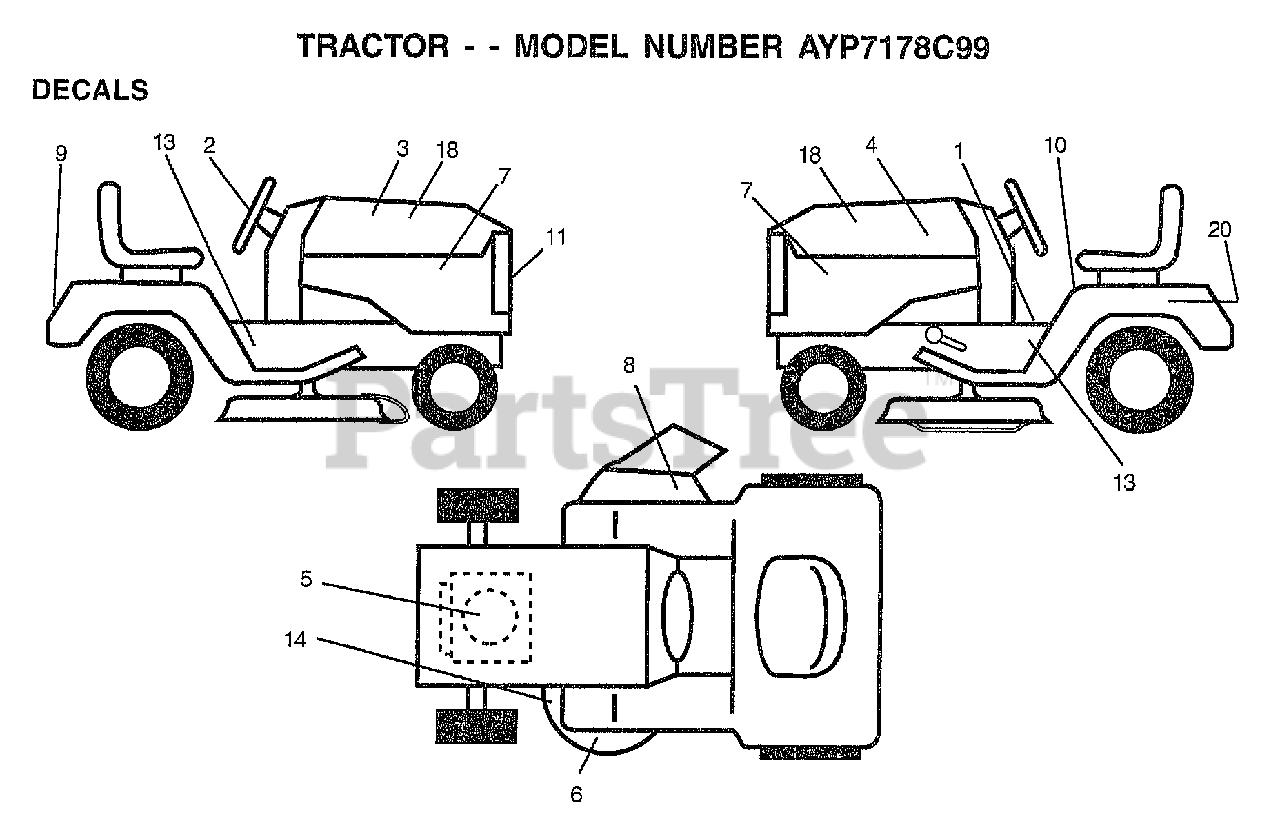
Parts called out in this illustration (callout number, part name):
1	"DECAL-DASH,OPER"
2	DECAL STEER WHL
3	DECAL HOOD RH
4	DECAL HOOD LH
5	DECAL, HP ENGINE
6	DECAL DECK MULCH
7	DECAL.SIDE PANEL
8	DECAL DECK WIZ +
10	"DECAL DANGER,FEND"
11	DECAL.LENS.WIZARD
13	DECAL CHASSIS WIZ
14	"DECAL-SCHEM,BELT"
18	NAMEPLATE.HD.WIZA
20	DECAL.BATRY.3-3908
